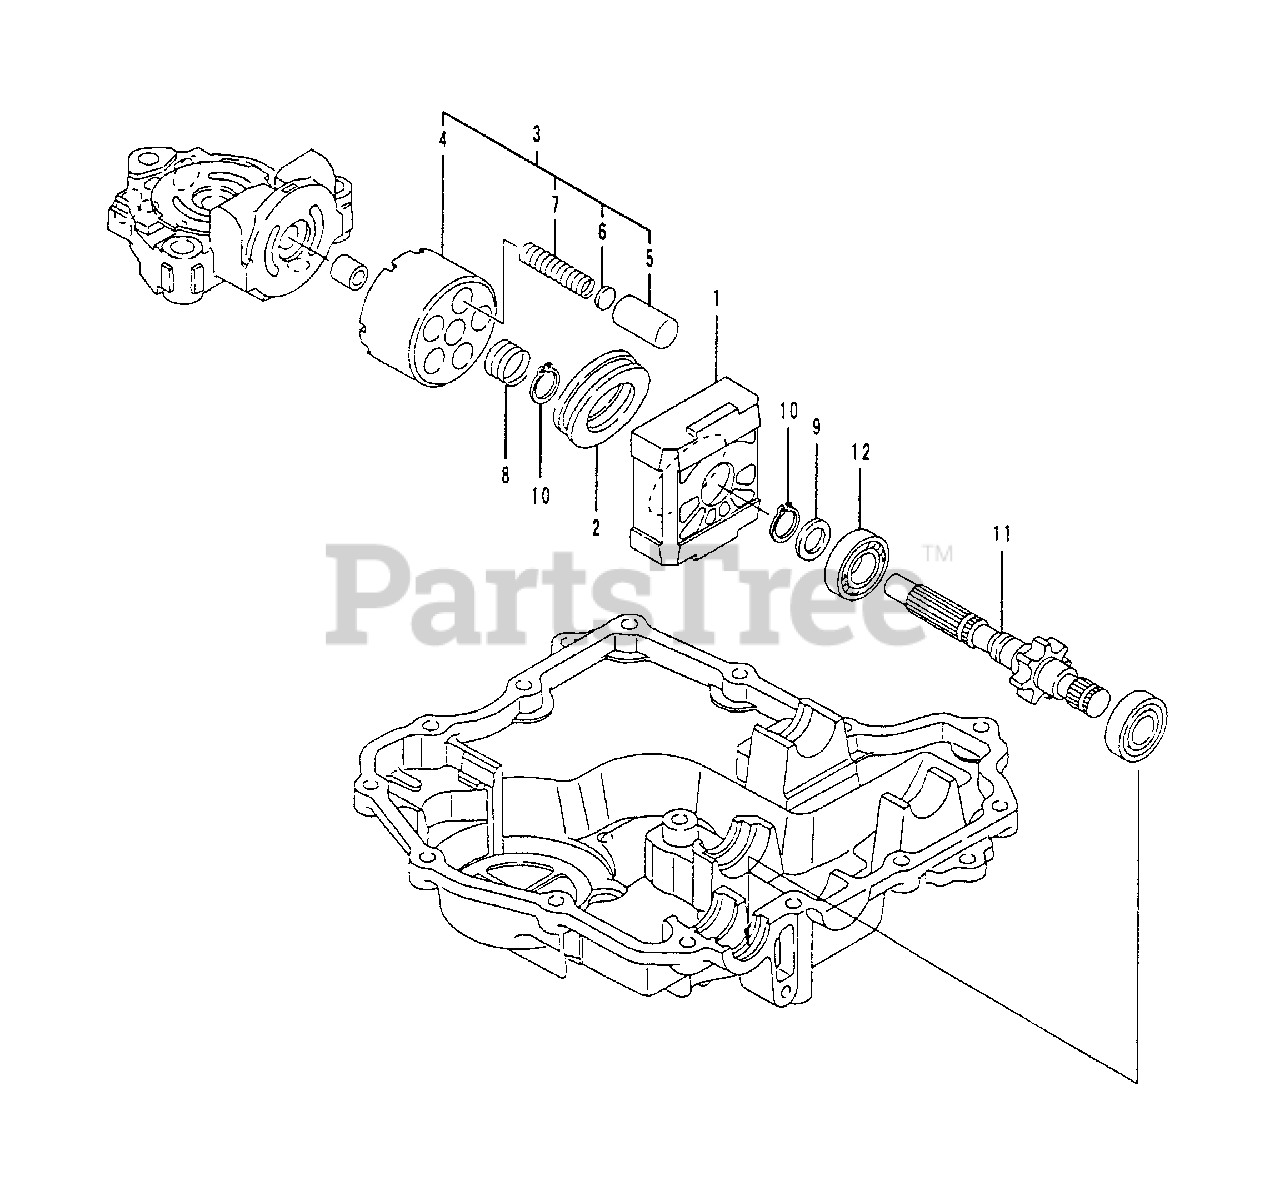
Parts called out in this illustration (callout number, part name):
2	BEARING (THRUST
3	CYLINDER BLOCK CMP
4	CYLINDER BLOCK
5	PISTON
6	WASHER 11
7	SPRING (PISTON
9	WASHER 15 X 20 X 1
11	SHAFT (MOTOR 13
12	BEARING 6202C3
